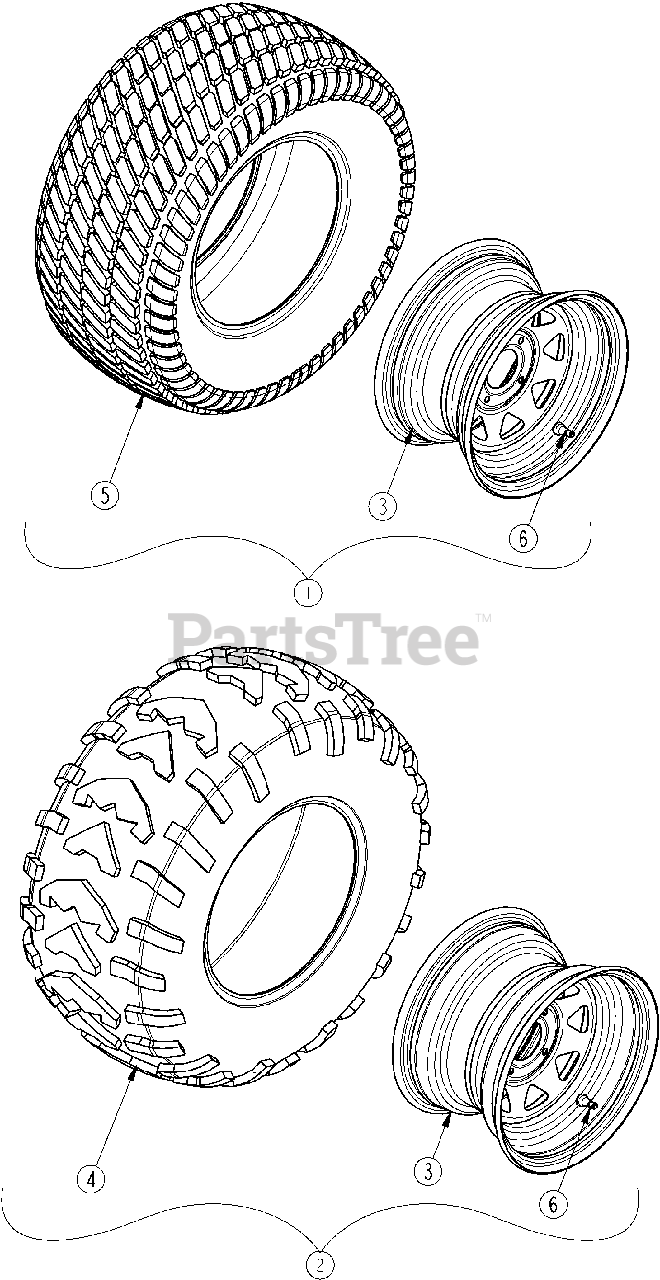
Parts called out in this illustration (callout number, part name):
1	TIRE/RIM REAR TURF 23-10.5-12
2	AT TIRE/RIM, GRAY RIGHT REAR
2	AT TIRE/RIM BLACK RIGHT REAR
2	AT TIRE/RIM, GRAY LEFT REAR
2	AT TIRE/RIM BLACK LEFT REAR
3	RIM 12X8.5 4-4 BOLT GRAY
3	RIM 12X8.5 4-4 BOLT BLACK
4	TIRE 25 X 11 X 12 AT489
5	TIRE TURF 23-10.5-12
6	VALVE STEM TR415 X. 625 X 1 1/4 LG
